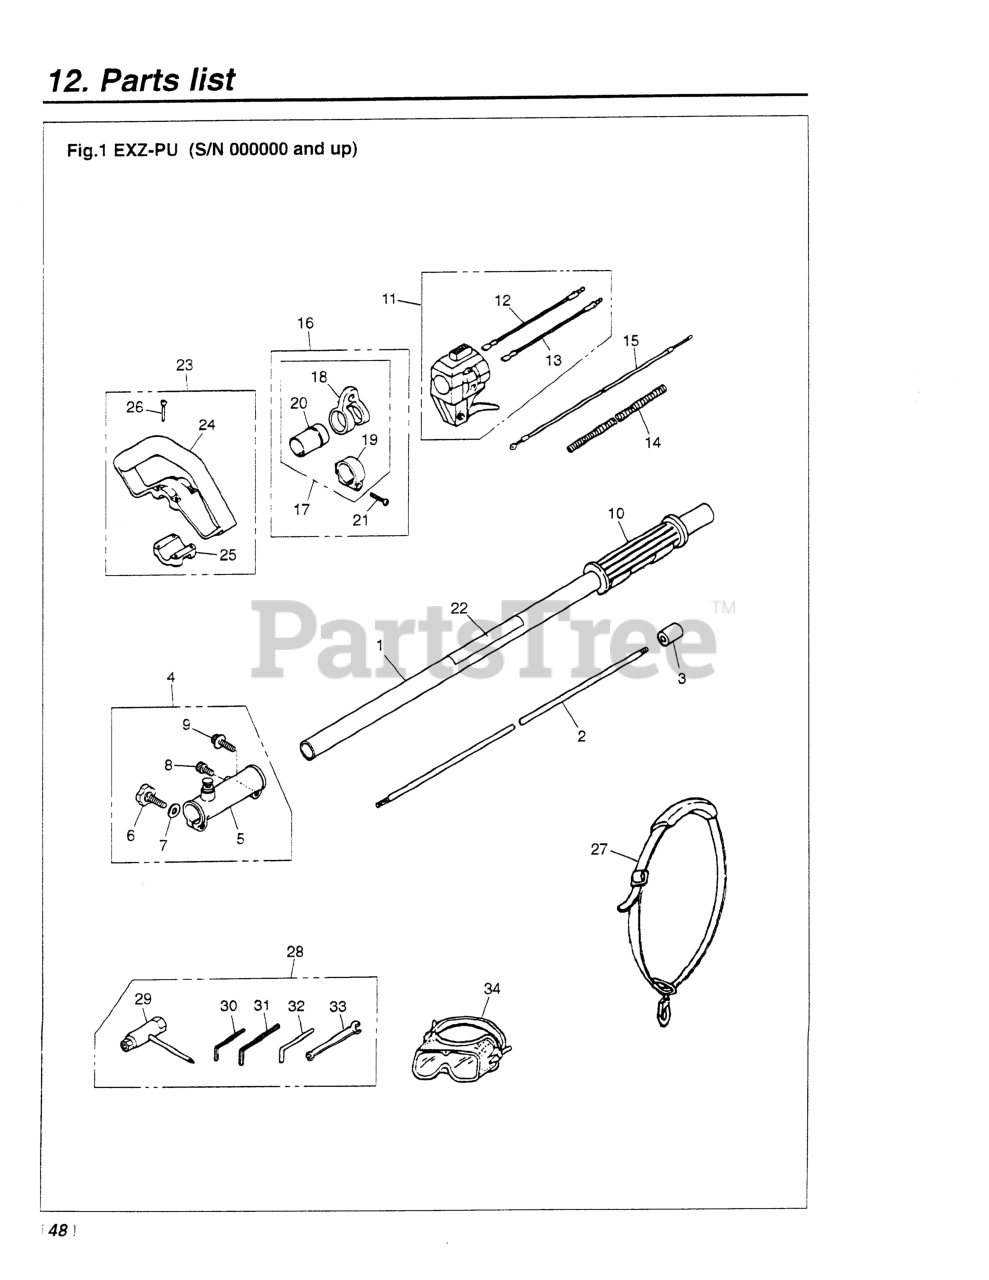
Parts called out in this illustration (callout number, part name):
1	PIPE COMPLETE
2	SHAFT
3	SPACER
4	JOINT, PIPE ASSY
5	JOINT
6	BOLT, KNOB
7	WASHER, M8 x 2.3 (RPLS -20823)
8	BOLT, M5 X 10
9	BOLT, M6 x 1.35
10	GRIP (RPLS 3577-32140 & 3220-
12	CORD (A), BLACK
13	CORD (B), RED
14	TUBE (RPLS 4900-72141)
15	CABLE (RPLS 5580-83100)
16	HANGER ASSEMBLY
17	HANGER COMPLETE
18	HANGER
19	CLAMP
20	SLEEVE
21	SCREW, M5 x 25
22	PLATE, NAME (EXZ-PU)
23	HANDLE ASSEMBLY
24	HANDLE
26	SCREW, M5 x 35
29	SOCKET
30	WRENCH (TOOL)
31	WRENCH (TOOL)
32	BAR
33	SPANNER, 8 X 10 (RPLS 2540- )
34	GOGGLE
